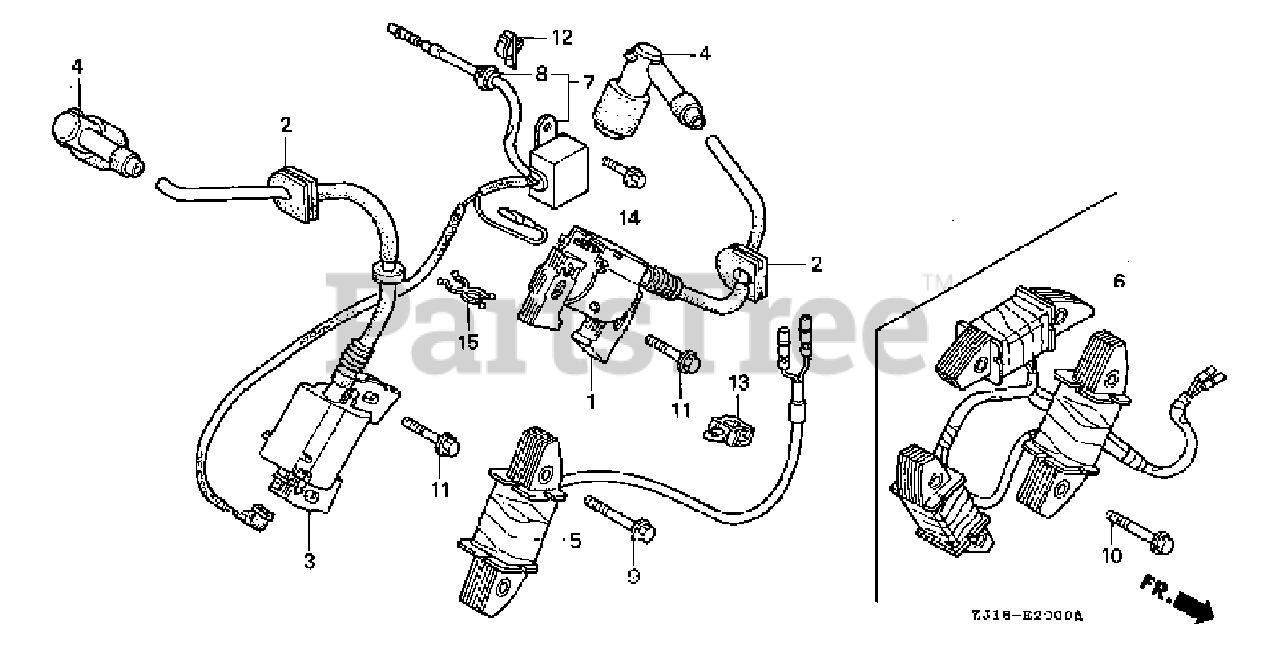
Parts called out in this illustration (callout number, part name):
1	COIL ASSY., R. IGNITION
2	GROMMET, IGNITION WIRE
3	COIL ASSY., L. IGNITION
4	CAP ASSY., NOISE SUPPRESSOR
5	COIL ASSY., CHARGE (12V/3A)
7	DIODE ASSY., ENGINE STOP
8	GROMMET, TOOL
9	BOLT, FLANGE (6X35)
11	BOLT, FLANGE (6X25)
12	CLIP, CORD
13	CLIP, WIRE HARNESS
14	BOLT, FLANGE (6X8)
15	CLIP, WIRE HARNESS
